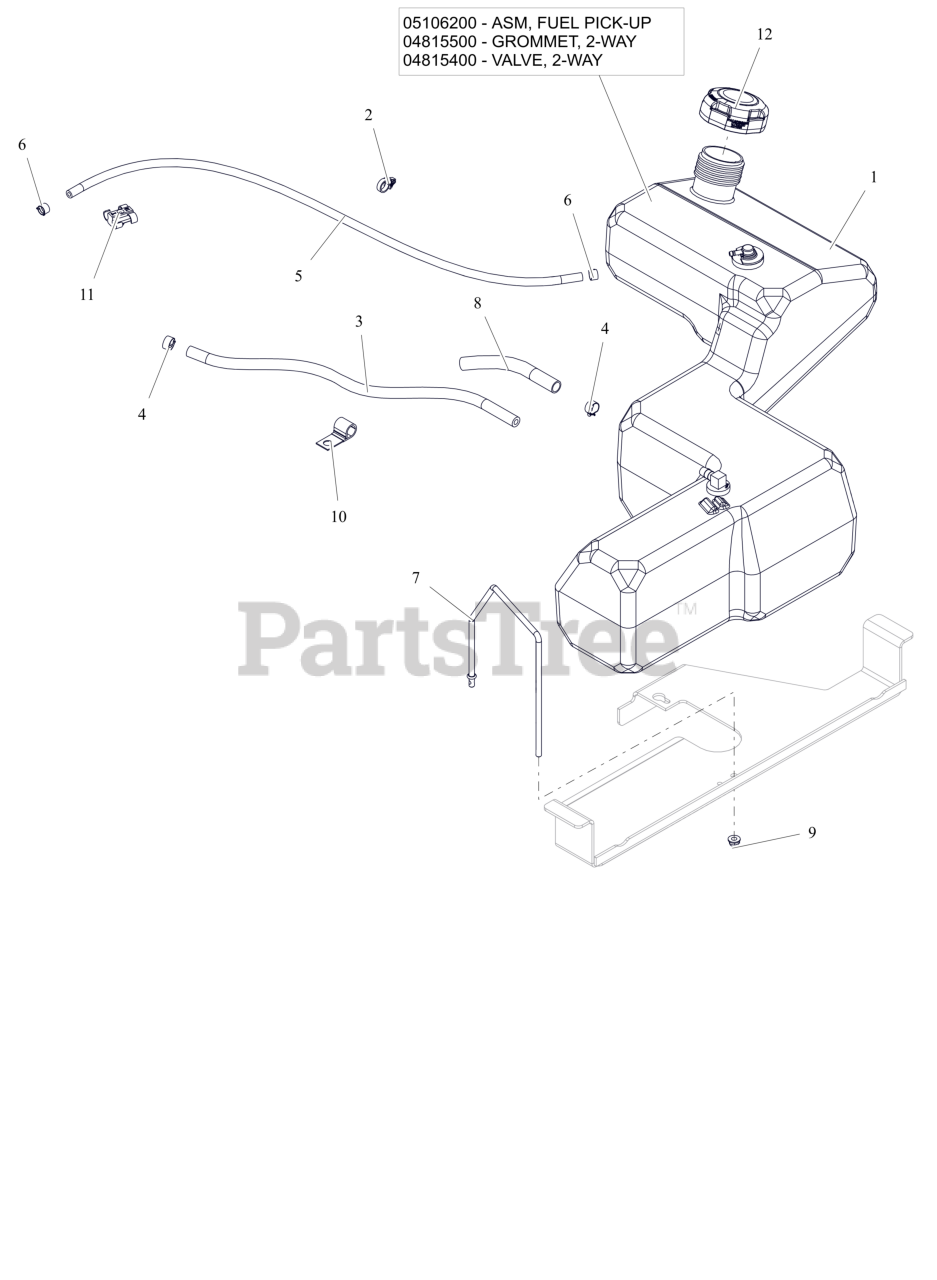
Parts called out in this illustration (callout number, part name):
1	ASM, FUEL TANK-IKON
1	ASM, IKON FUEL PICK-UP
1	GROMMET, 2-WAY
1	VALVE, 2-WAY
2	ROUTING CLIP (1/2" ID)
3	HOSE, .25 LOW-PERM BULK GAS
4	CLAMP, FUEL LINE
5	HOSE, .188 LOW-PERM BULK GAS
6	CLAMP-HOSE, SPRING .188
7	BRKT, FUEL TANK HOLD DOWN
8	WRAP, ANTIABRASION .5X.064WALL
9	NUT,NYL-FLG .25-20 GF ZCC
10	J-CLAMP
11	CLIP, T, .38-.50
12	CAP, FUEL - 2.25 RATCHET INLET VENT
